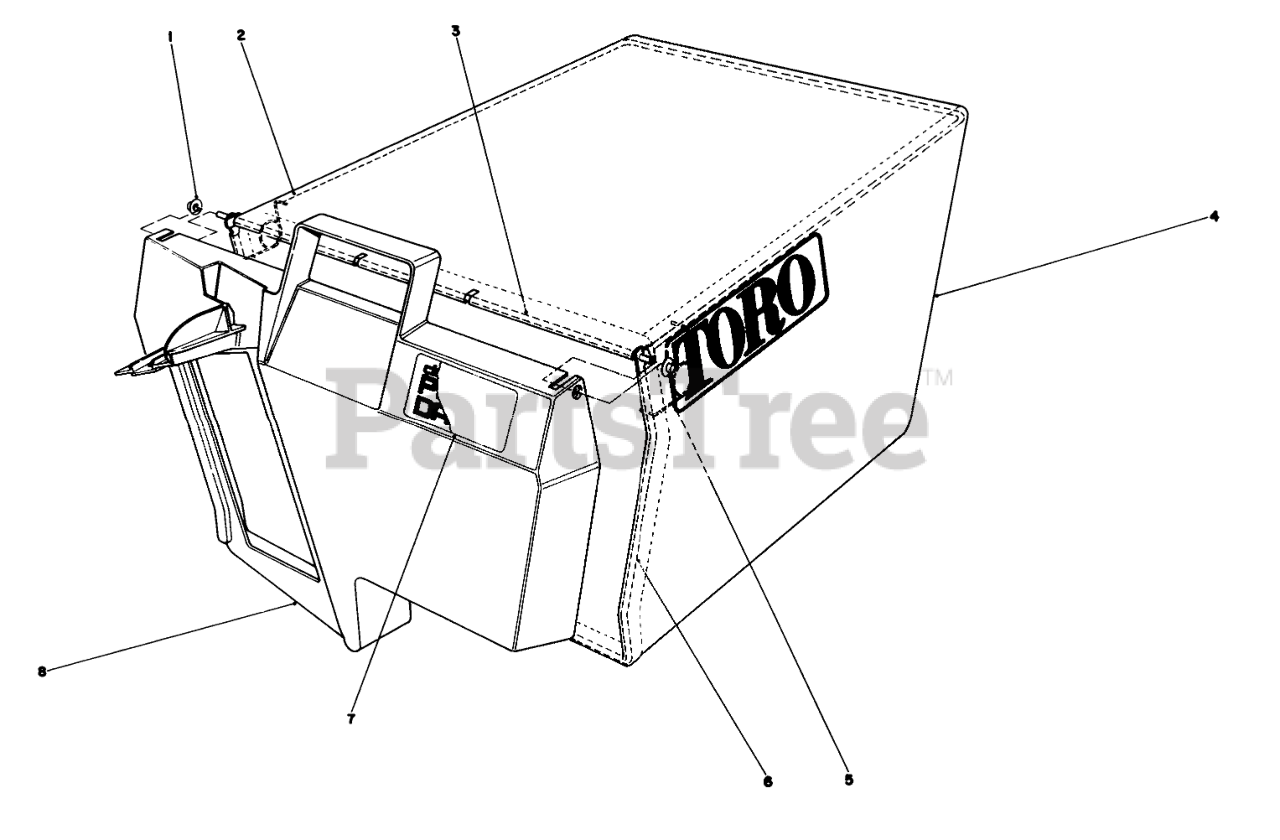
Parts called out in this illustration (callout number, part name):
1	NUT-PUSH
2	FRAME-BAG, UPPER
3	HINGE-DOOR, BAG
4	Bag
5	SPRING
6	Frame Bag
7	BAG DOOR DECAL
8	2 Door-Grass Bag
